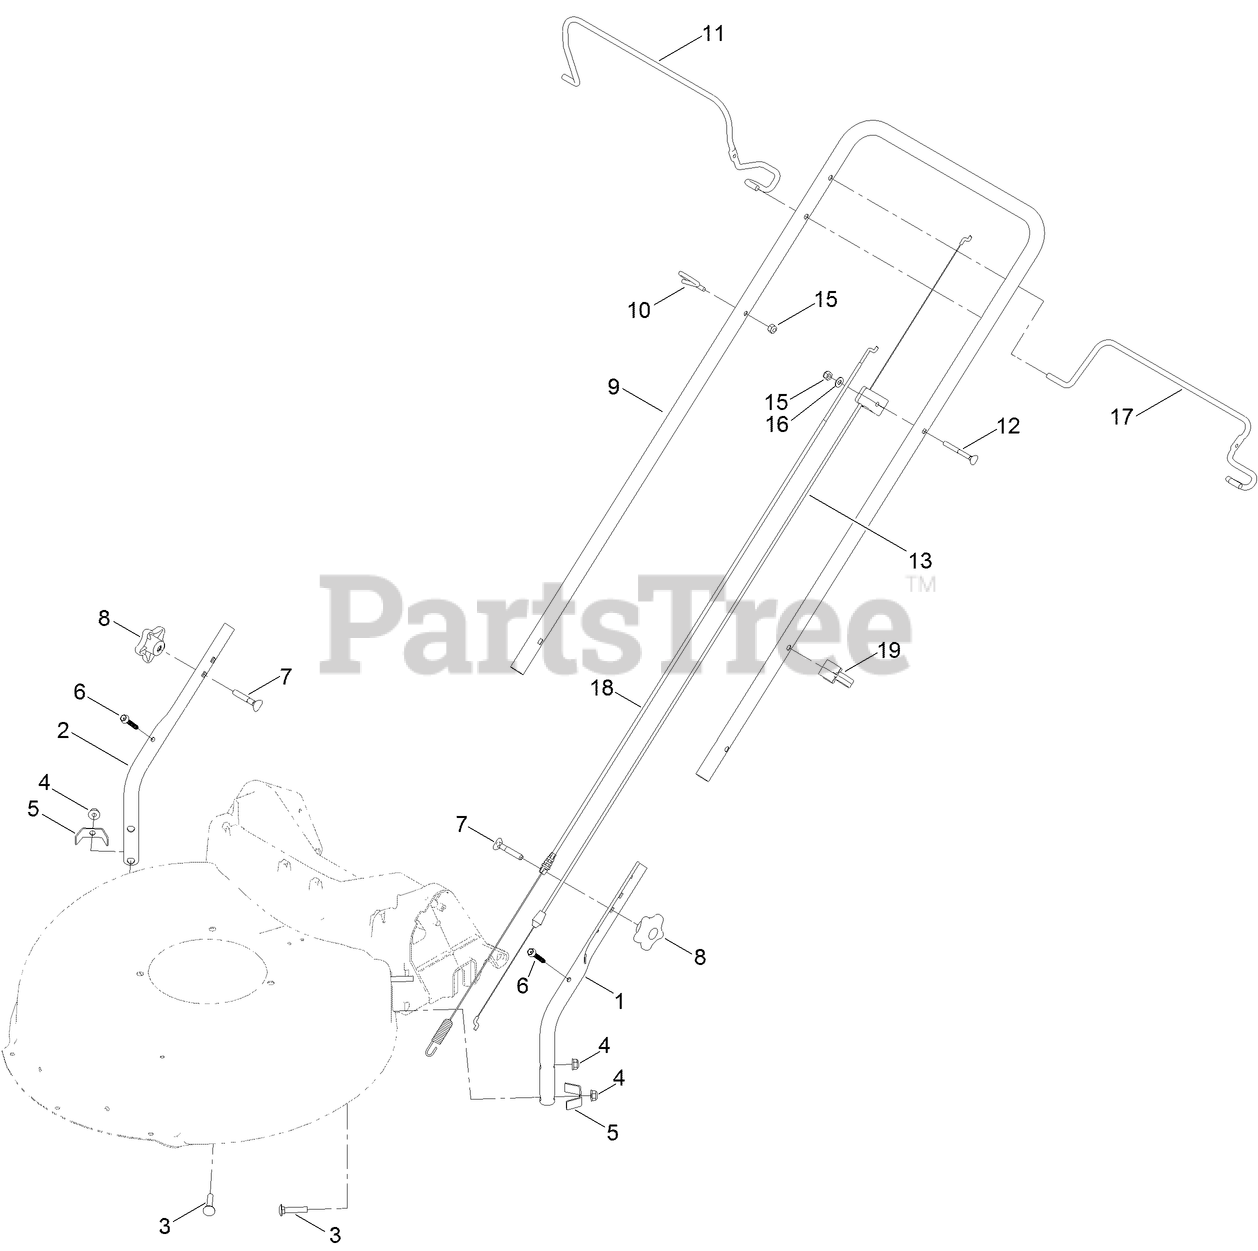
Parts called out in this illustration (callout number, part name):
1	HANDLE-LOWER, LH
2	HANDLE-LOWER, RH
3	BOLT-CARR
4	NUT-FLANGE, NI
5	BRACKET-CHUTE
6	SCREW-FLANGE, SERRATED
7	SCREW-HANDLE
8	KNOB-HANDLE
9	HANDLE-UPPER
10	GUIDE-ROPE
12	SCREW-HANDLE
13	CABLE-BRAKE
15	NUT-LOCK, NI
16	WASHER-FLAT
17	BAIL-TRACTION
18	CABLE-TRACTION
19	GUIDE-CABLE
